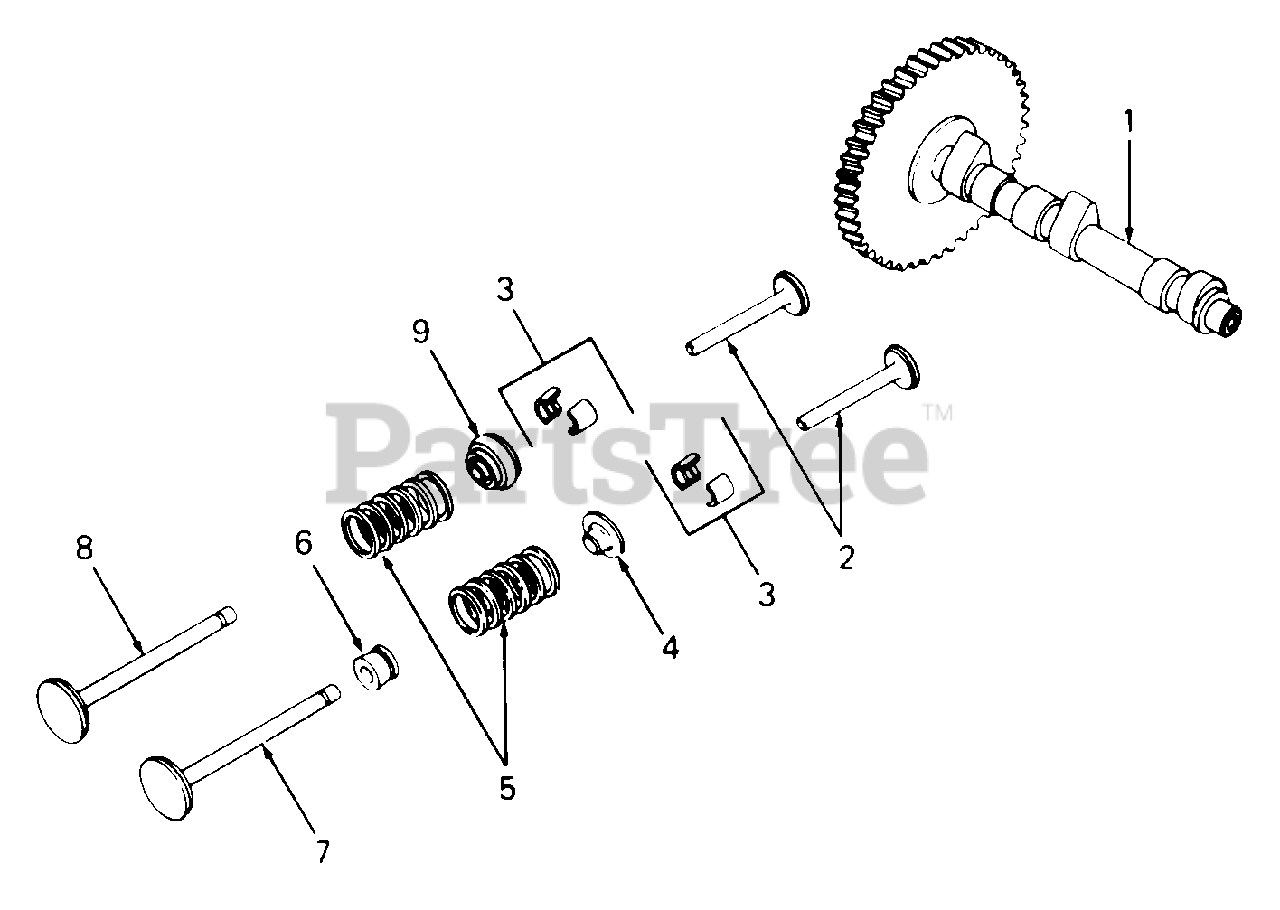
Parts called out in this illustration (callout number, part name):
1	Camshaft
3	Kit, Retainer
4	Retainer, Intake Valve
5	Spring, Valve
6	Seal, Intake Valve Stem
7	Valve, Intake
8	Valve, Exhaust
9	Rotator, Exhaust Valve
